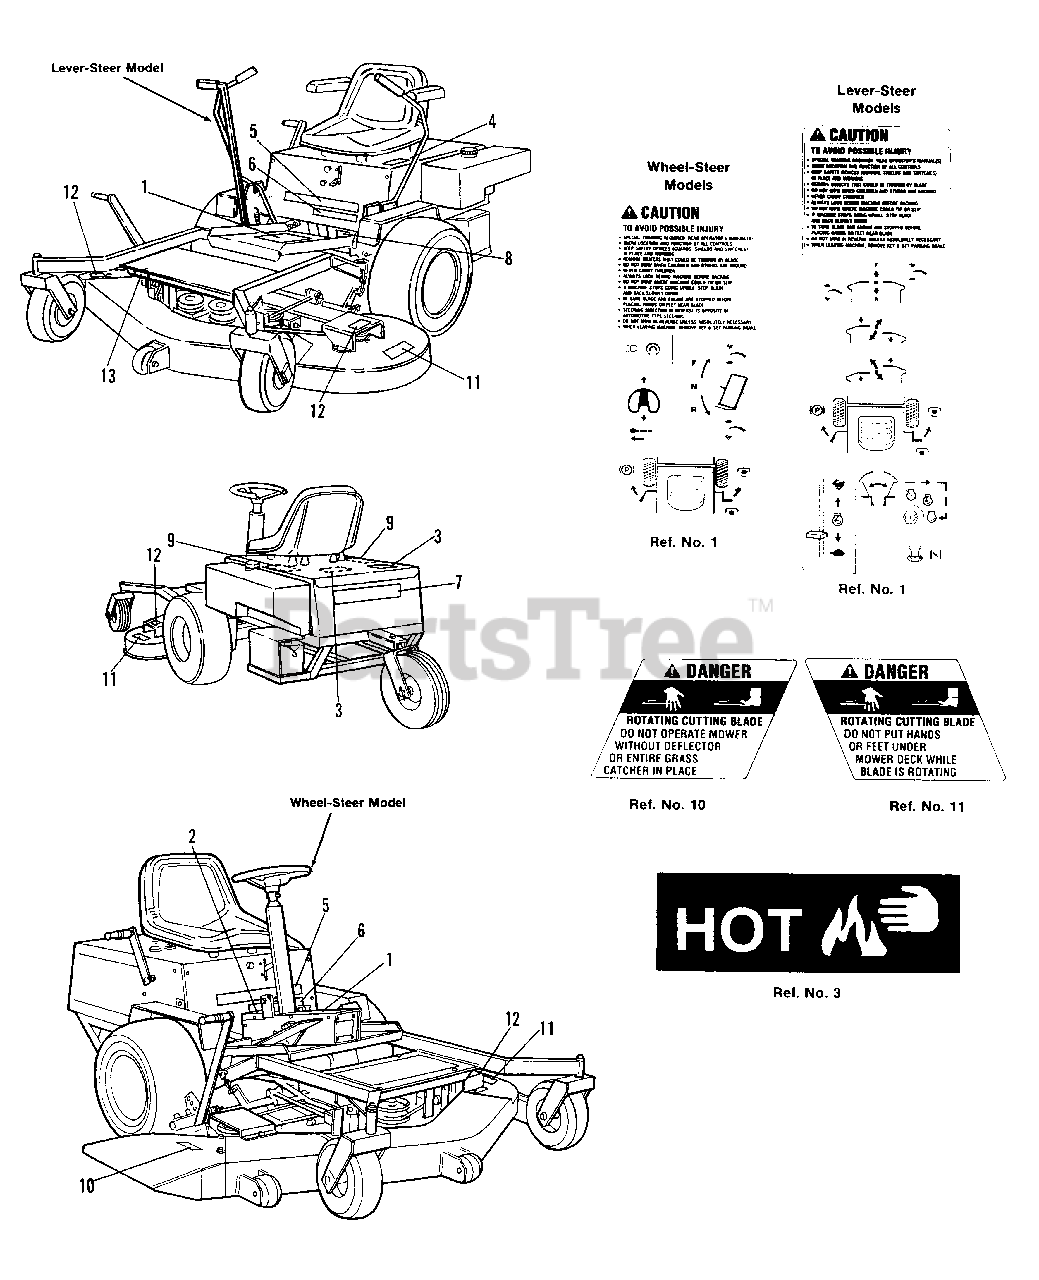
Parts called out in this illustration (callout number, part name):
1	DECAL, Caution & Controls (Wheel-Steer Models)
1	DECAL, Caution & Controls (Lever-Steer Models)
2	DECAL, Starting Instructions (Wheel-Steer Models)
3	DECAL, Hot (Located under seat deck)
4	DECAL, Rear Frame (16 HP)
4	DECAL, Rear Frame (18 HP)
4	DECAL, Rear Frame (20 HP)
5	DECAL, Simplicity
6	DECAL, Professional (Black)
7	DECAL, Simplicity
8	I.D. PLATE
9	DECAL, Tow Control (Located on Hydro Pump tow latches)
10	DECAL, Danger
11	DECAL, Danger
12	DECAL, Width, 46"
12	DECAL, Width, 54"
12	DECAL, Width, 60"
12	DECAL, Width, 66"
13	I.D. PLATE
